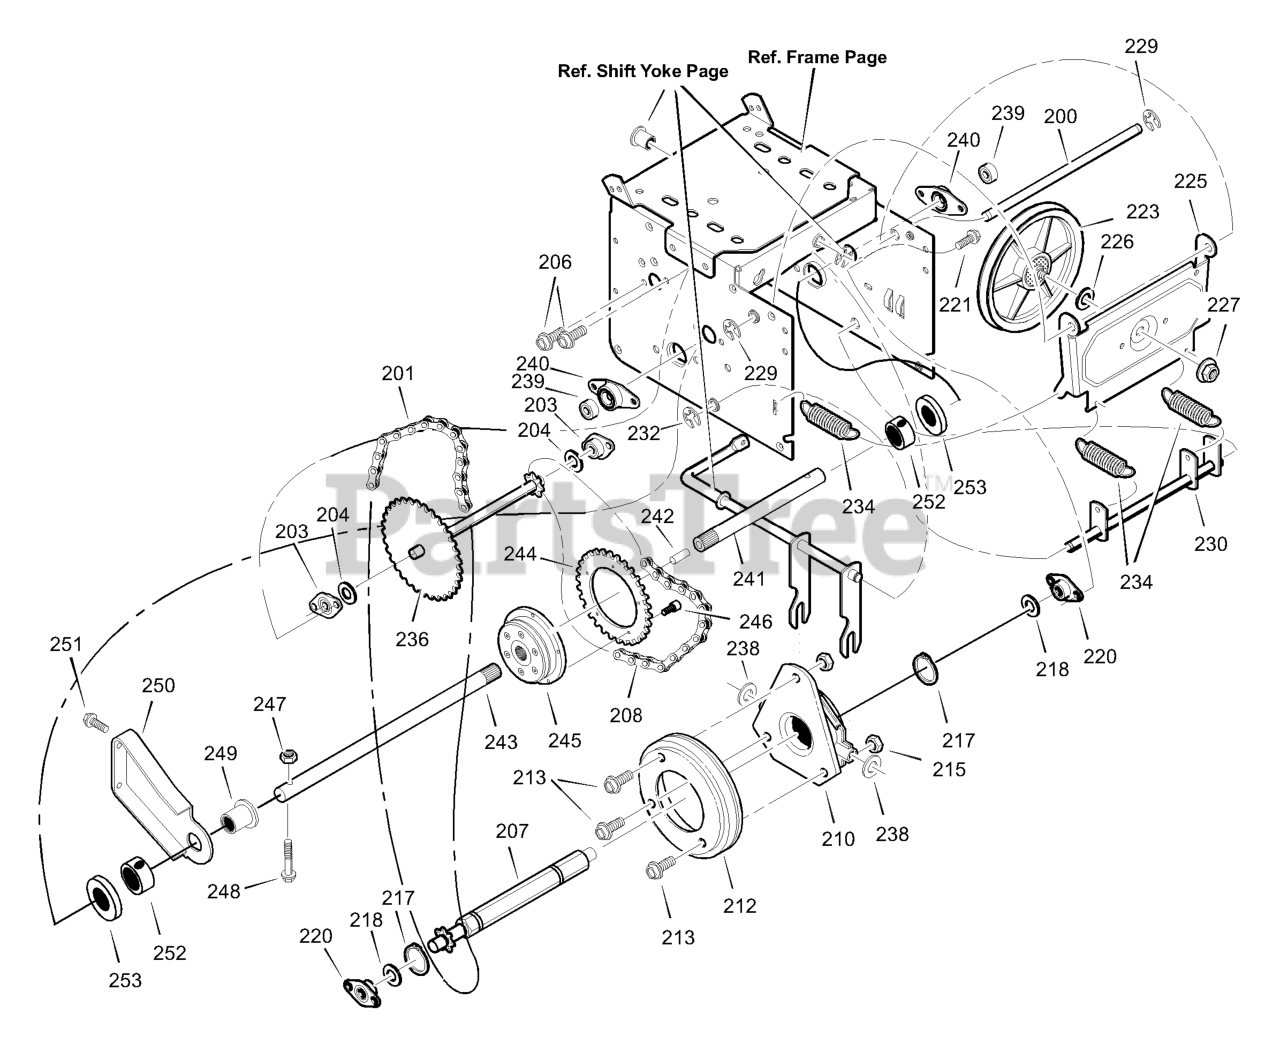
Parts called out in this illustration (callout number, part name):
200	LF AXLE, SWING PLATE YZ
201	CHAIN, ROLLER #420x19.00
203	BEARING AND RETAINER, ASSY
206	SCREW, TAP 5/16-18 x 0.5
207	ASSY, HEX SHAFT
208	CHAIN, ROLLER #420x18.00 LG
210	BEARING, TRUNION CLUTCH R
212	WHEEL, FRICTION DISC
215	NUT, KEPS HEX 1/4-20
217	RING, RETEXT
220	BEARING AND RETAINER, ASSY
221	SCREW, TAP 5/16-18 x .5
223	FRICTION PULLEY
225	LF PLATE, SWINGING YZ
226	SPACER, FRICTION PULLEY
227	NUT, FLANGE LOCK 3/8-24
229	RETAINER, RING
230	LF ASSY, SPRING LINK YZ
232	RETAINER, RING
234	SPRING, EXTENSION
236	SET, SPROCKET 33T/7
238	WASHER, FLAT
239	BEARING, BALL
240	RETAINER, BEARING
241	AXLE AND BUSHING, LEFT
242	PIN, AXLE
243	AXLE AND BUSHING, RIGHT
244	SPROCKET
245	CLUTCH, AUTO LOCK
247	NUT
248	BOLT
249	BEARING, AXLE
250	BRACKET, AXLE SUPPORT
251	SCREW
252	COLLAR, LOCKING
